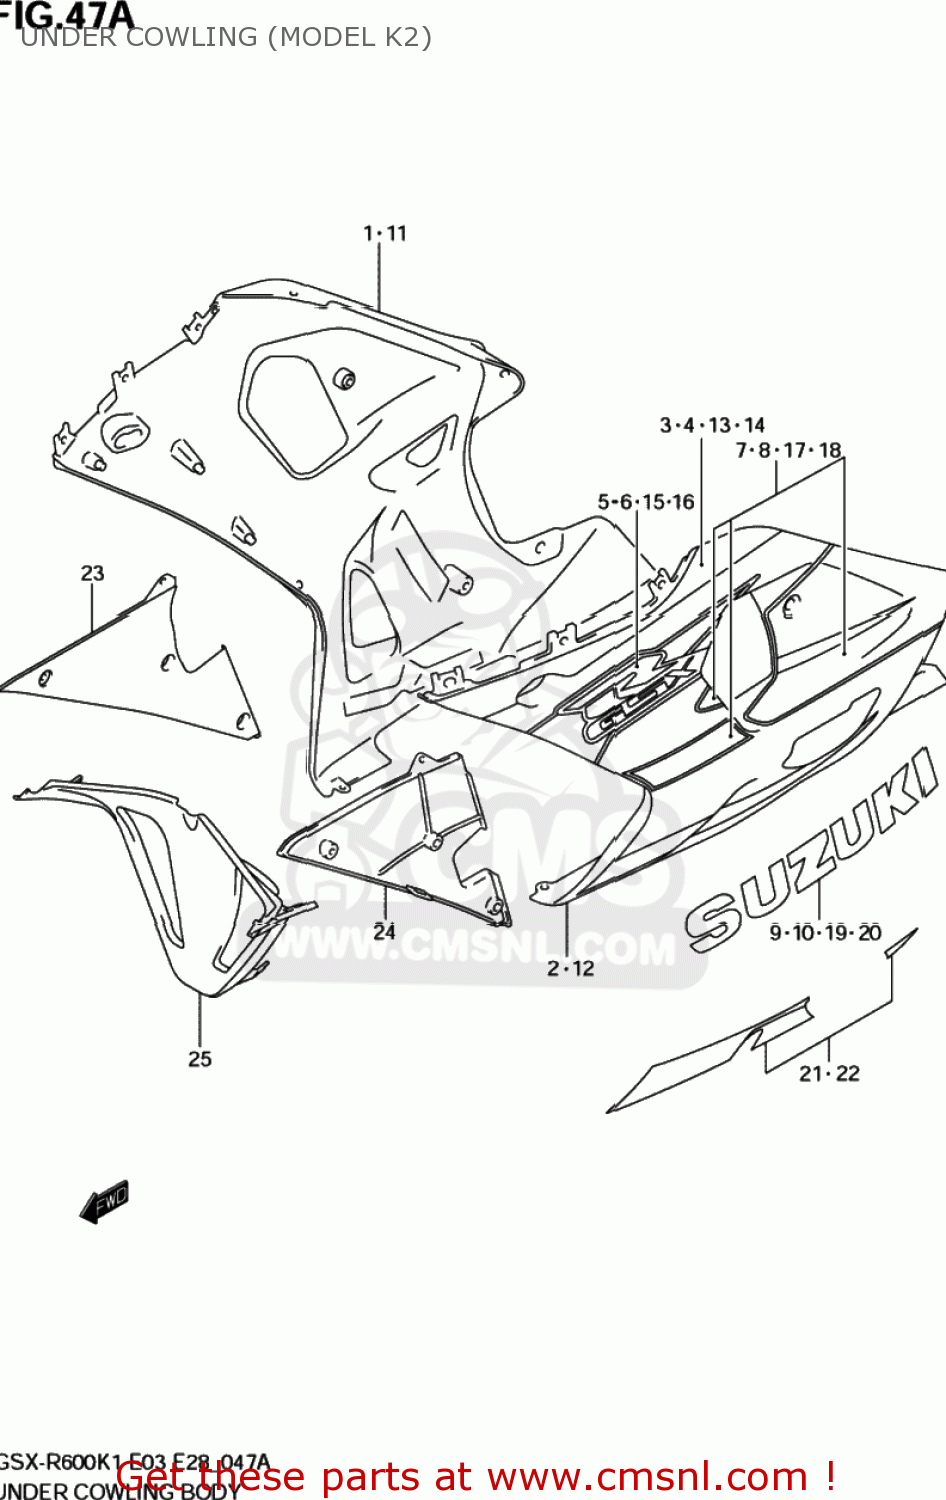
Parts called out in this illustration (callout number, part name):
1	COWLING ASSY,UNDER,R
2	COWLING ASSY,UNDER,L
3	TAPE,UNDER UPR,R
4	TAPE,UNDER UPR,L
5	TAPE(GSXR),COWL UNDER,R
6	TAPE(GSXR),COWL UNDER,L
7	TAPE SET,COWL MIDDLE,R
8	TAPE SET,COWL MIDDLE,L
9	EMBLEM SET,SUZUK,R
10	EMBLEM SET,SUZUK,L
11	COWLING ASSY,UNDER,R
12	COWLING ASSY,UNDER,L
13	TAPE,UNDER UPR,R
14	TAPE,UNDER UPR,L
15	TAPE(GSXR),COWL UNDER,R
16	TAPE(GSXR),COWL UNDER,L
17	TAPE SET,COWL MIDDLE,R
18	TAPE SET,COWL MIDDLE,L
19	EMBLEM SET,SUZUK,R
20	EMBLEM SET,SUZUK,L
21	TAPE SET,COWL LWR,R
22	TAPE SET,COWL LWR,L
23	COWLING,UNDER INNER,R
24	COWLING,UNDER INNER,L
25	COWLING,UNDER CTR
